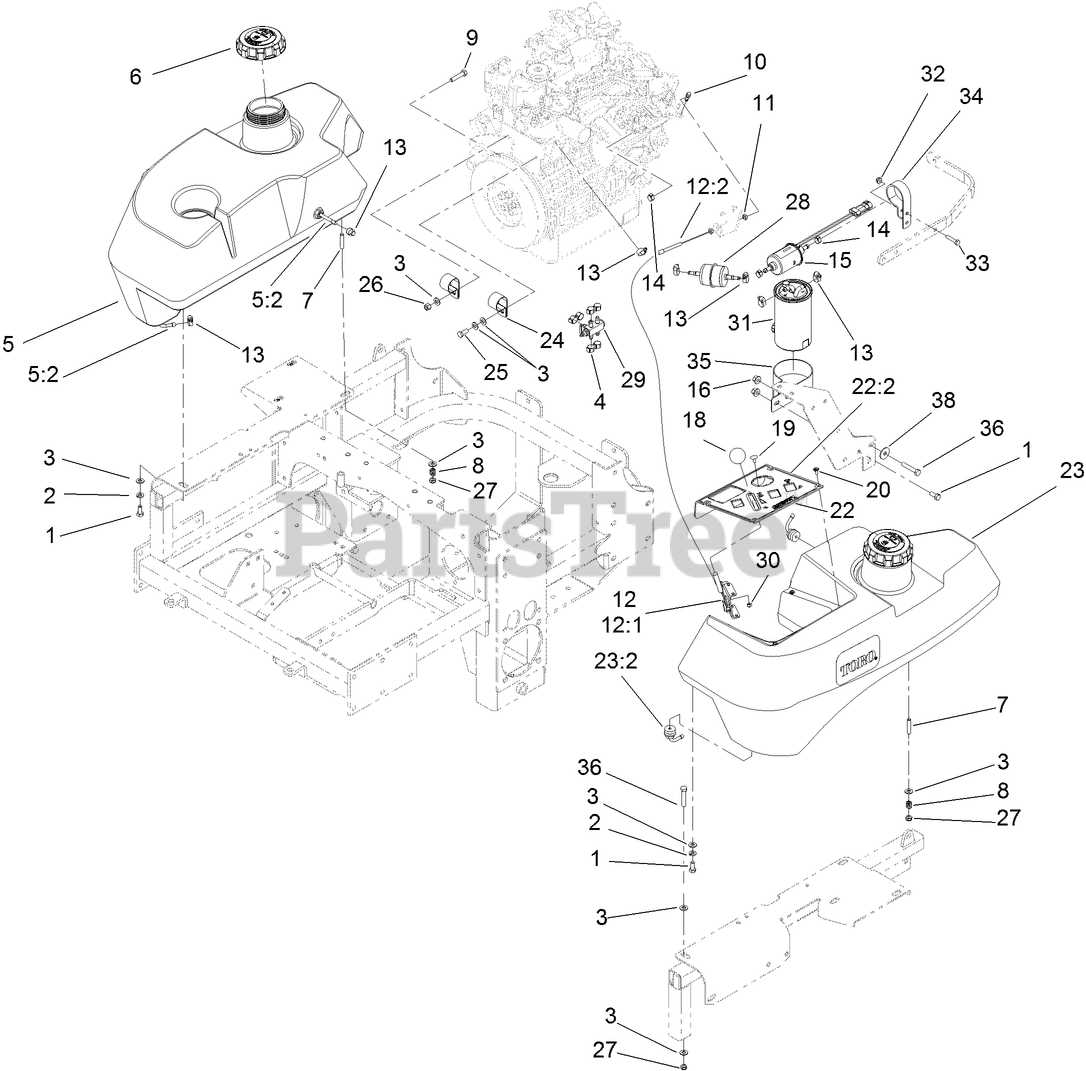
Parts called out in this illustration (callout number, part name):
1	SCREW-HH
2	WASHER-LOCK
3	WASHER-PLAIN
4	CLAMP-HOSE, FUEL
5	RH FUEL TANK ASM
5:2	Fitting-Fuel, Bulkhead
6	BIODIESEL CAP ASM
8	SPRING-TANK, FUEL
9	SCREW-HH
10	SWIVEL-STOP, CABLE
11	NUT-JAM
12	THROTTLE CONTROL ASM
12:1	LEVER-THROTTLE
12:2	CABLE-THROTTLE
13	CLAMP-WORM
14	CLAMP-HOSE, FUEL
15	PUMP-FUEL
16	NUT-LOCK, NI
18	KNOB-BALL
19	BOLT-CARR
20	SCREW-PPH
22	CONTROL PANEL ASM
22:2	DECAL-PANEL, CONTROL
23	LH FUEL TANK ASM
23:2	Fitting-Fuel, Bulkhead
24	CLIP-LOOM
25	SCREW-HH
26	NUT-LOCK, NI
27	NUT-LOCK, NI
28	FILTER-INLINE
29	VALVE-FUEL, DUAL FLOW
30	NUT-LOCK, NI
31	ELEMENT-FILTER, FUEL/WATER
32	NUT-HF
33	SCREW-HH
34	BRACKET-PUMP, FUEL
35	BRACKET-FILTER, FUEL
36	SCREW-HH
38	WASHER-FLAT
